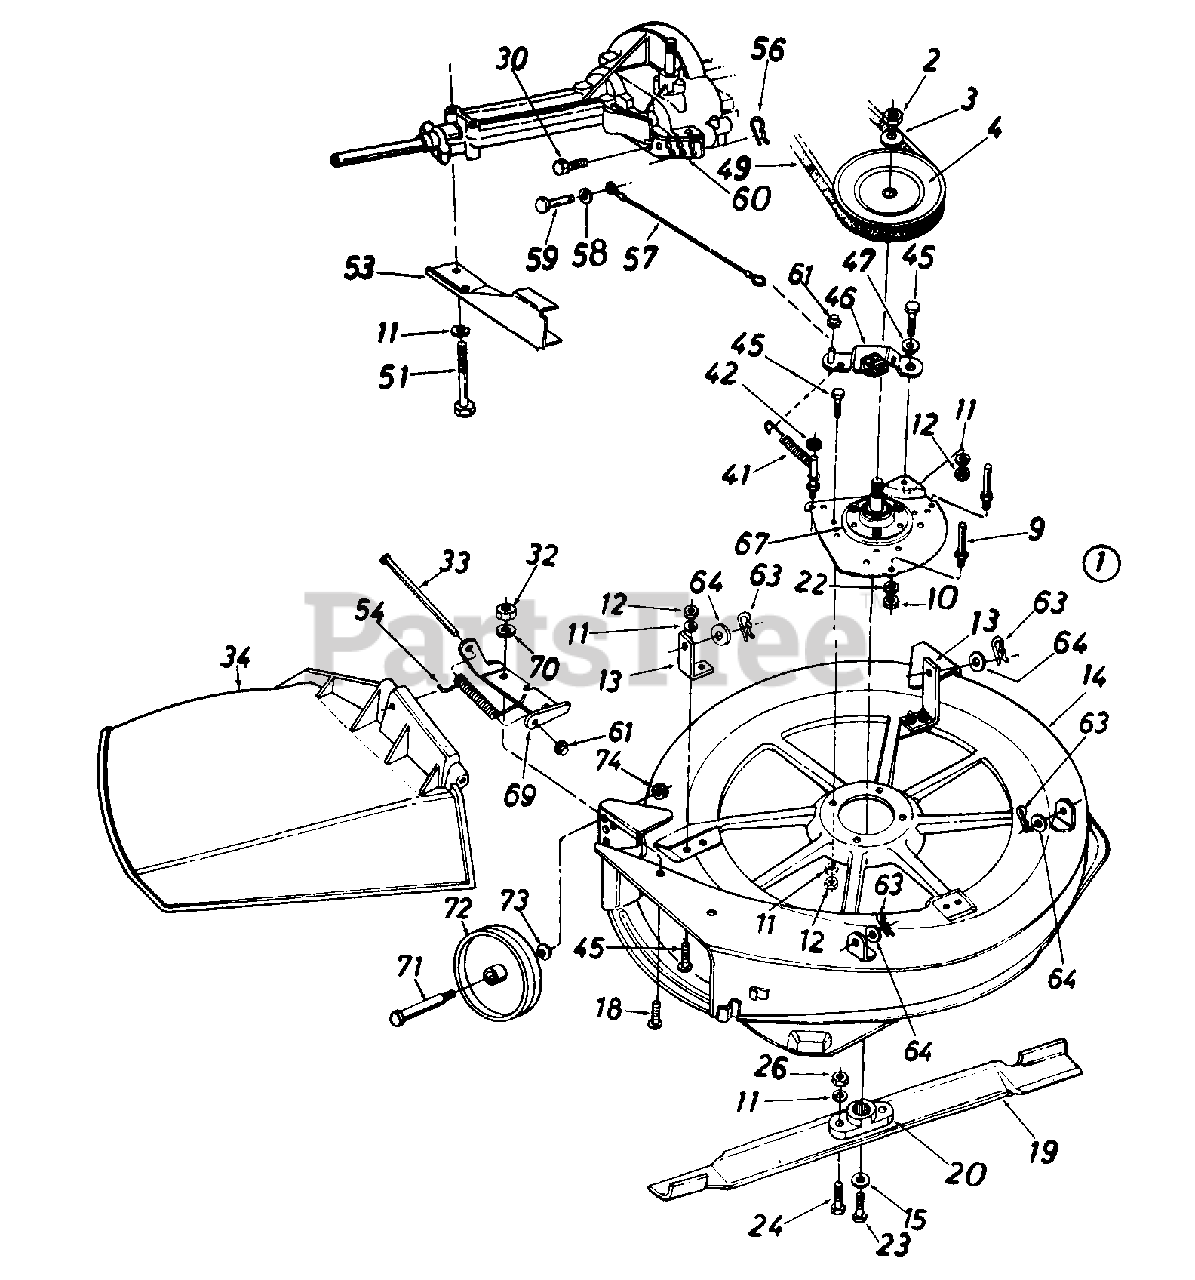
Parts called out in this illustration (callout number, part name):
3	Bell-Wash. .630" I.D. x 1.25"
4	5/8 V-Pulley .75" I.D. x 7"
9	Stud 3/8-16 x 2.75" Lg.
10	Hex Jam Nut 3/8-16 Thd.
11	L-Wash. 5/16" I.D.
12	Hex Nut 5/16-18 Thd.
18	Hex Bolt 1/4-20 x .62" Lg.
19	30" High Lift Blade
20	Blade Adapter
22	L-Wash. 3/8" I.D.
23	Hex Bolt 3/8-24 x 1.0"
24	Hex Bolt 5/16-24 x 1.0" Lg.
26	Hex Nut 5/16-24 Thd.
30	Hex Bolt 1/4-20 x 50" Lg.
32	Hex Nut 1/4-20 Thd.
33	Hinge Pin
34	Chute Ass'y. Comp.
41	Extension Spring
42	Push Speed Nut
45	Hex Bolt 5/16-18 x .75"
46	Blade Brake Brkt. Ass'y.
47	Shoulder Spacer .500" Dia.
49	"V"-Belt
51	Hex Bolt 5/16-18 x 2.75"
56	Int. Cot. Pin 5/16" Dia.
57	Brake Cable 9.75" Lg.
58	Fl-Wash. .281" I.D. x .50"
59	Clevis Pin 1/4" Dia.
60	Lower Inside Belt Guard
61	Cap Speed Nut 1/4" Rod
63	Int. Cotter Pin 1/2" Dia.
64	Fl-Wash. .531" I.D. x .930"
67	Blade Spindle Ass'y. Comp.
69	Hinge Mtg. Brkt.
70	Bell-Wash. 1/4" I.D.
71	Shld. Scr. .498" x 1.53" Lg.
72	Deck Wheel
73	Bell-Wash. .38" I.D. x .88"
74	Hex L-Nut 3/8-16 Thd.
